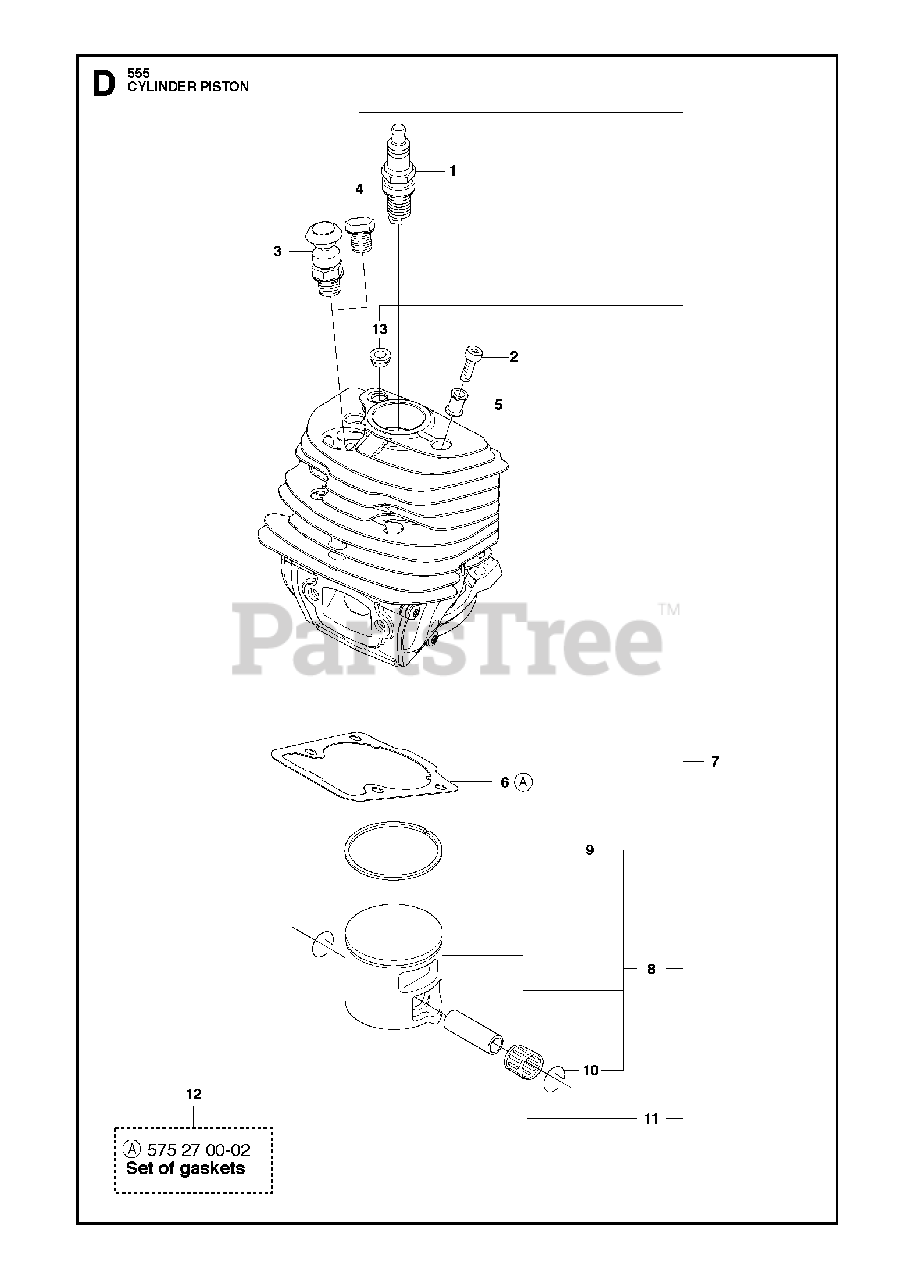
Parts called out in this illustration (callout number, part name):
1	CMR6H NGK SPARK PLUG
2	SCREW MC6S 5X35
3	DECOMPRESSION VALVE
4	CYLINDER PLUG
6	GASKET
7	CYLINDER-PISTON ASSY
8	PISTON ASSY
9	PISTON RING
10	LOCKING RING
11	NEEDLE BEARING
12	GASKET KIT
13	BUSHING
